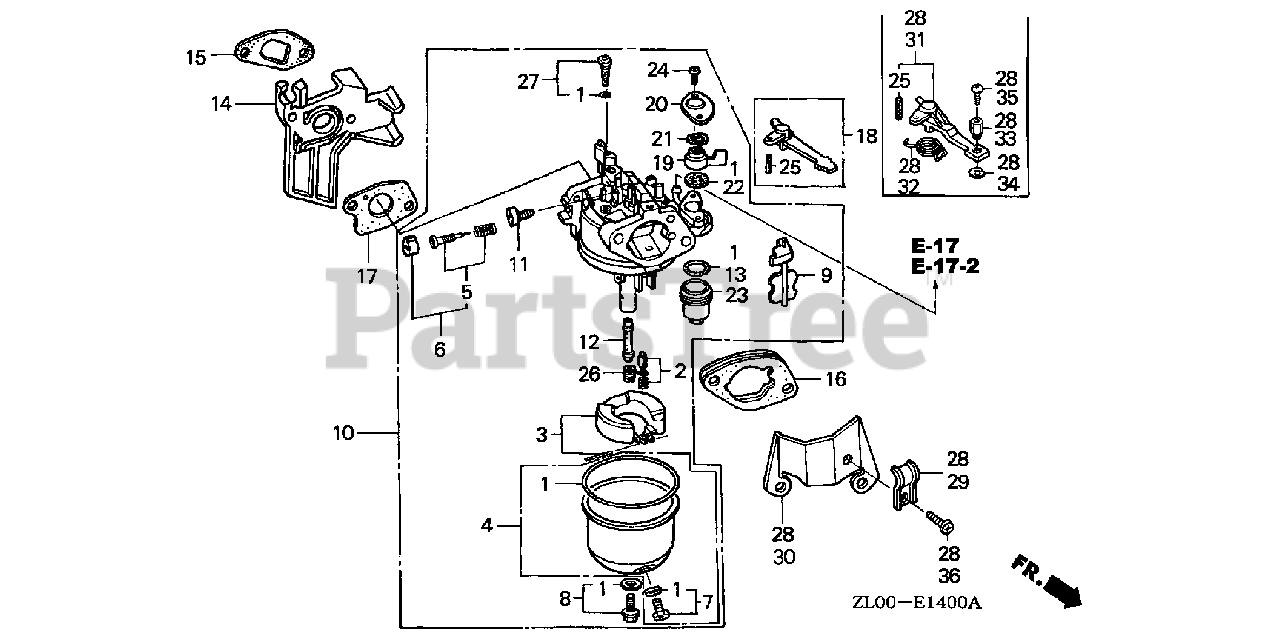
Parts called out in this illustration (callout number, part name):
1	GASKET SET
2	VALVE SET, FLOAT
3	FLOAT SET
4	CHAMBER SET, FLOAT
6	SCREW SET
7	SCREW SET, DRAIN
8	SCREW SET B
9	CHOKE SET
10	CARBURETOR ASSY. (BE64F B)
11	SCREW, THROTTLE STOP
12	NOZZLE, MAIN
13	GASKET, FUEL STRAINER CUP
14	INSULATOR, CARBURETOR
15	GASKET, INSULATOR
16	SPACER, CARBURETOR
17	GASKET, CARBURETOR
19	LEVER, VALVE
20	PLATE, LEVER SETTING
21	SPRING, VALVE LEVER
22	GASKET, VALVE
23	CUP, FUEL STRAINER
24	SCREW, PAN (3X6)
25	PIN, SPRING (2X12)
26	JET, MAIN (#70)
26	JET, MAIN (#72)
26	JET, MAIN (#75)
27	JET SET, PILOT (#45)
29	HOLDER, CONTROL CABLE
30	STAY, CHOKE CONTROL
31	LEVER, CHOKE (REMOTE)
32	SPRING, RETURN
33	HOLDER, CABLE
34	CIRCLIP (5MM)
35	SCREW, PAN (4X8)
36	SCREW, PAN (5X8)
